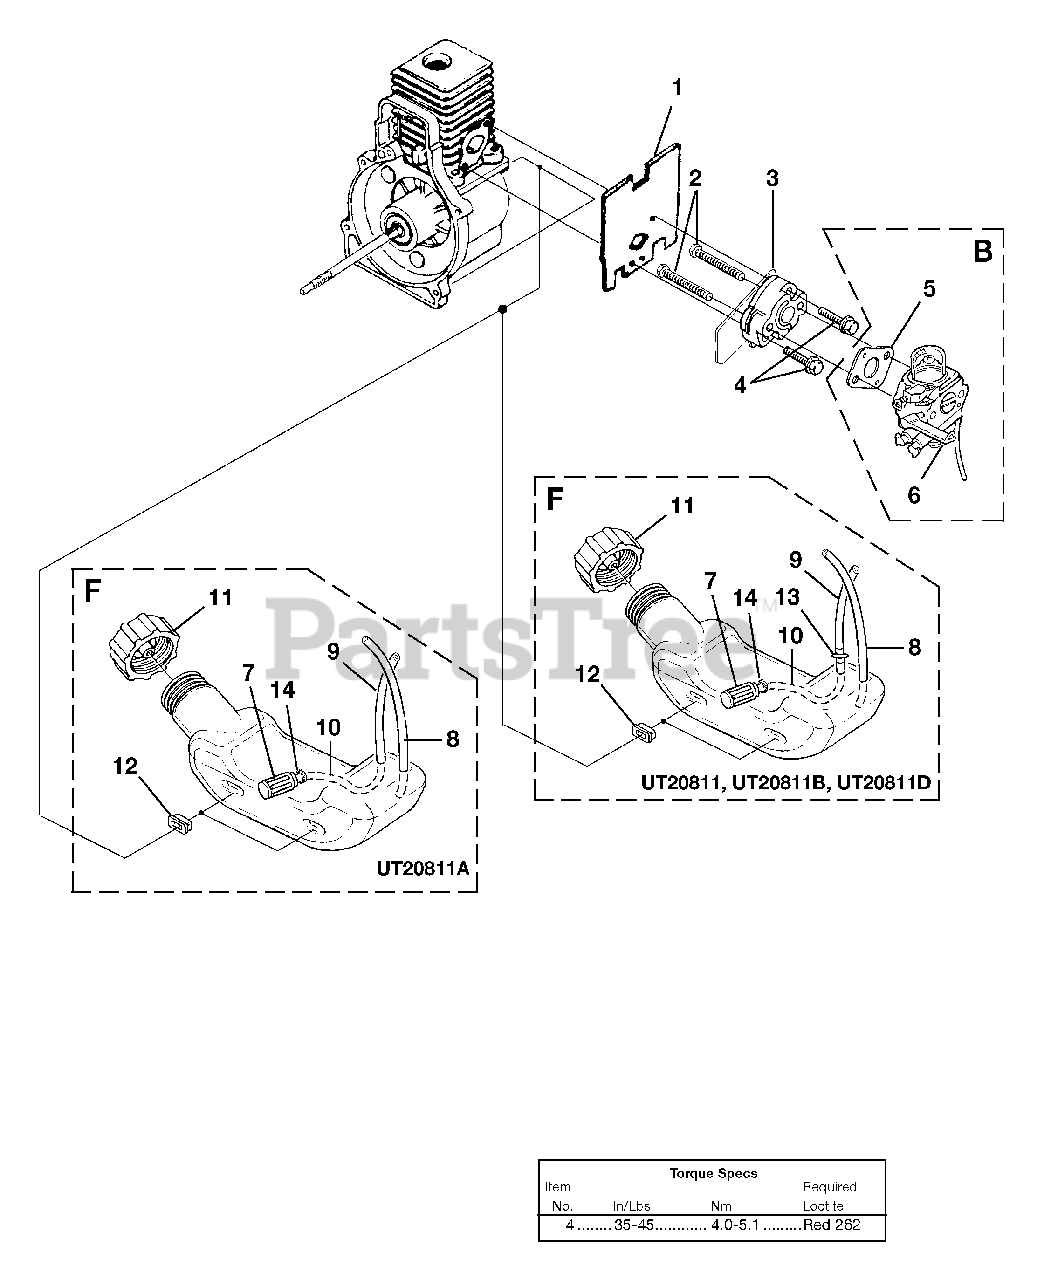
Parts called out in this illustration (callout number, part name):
1	GASKET-Heat Dam
2	SCREW-Machine (10-24 X 2 1/4")
3	HEAT DAM
4	SCREW-Sems (10-24 X 1")
5	GASKET-Carburetor
6	LEVER-Choke
7	FILTER-Fuel
8	TUBING-Rubber
8	TUBING-Rubber (6")
9	TUBING-Rubber
9	TUBING-Rubber (7.75")
10	TUBING-Rubber
11	FUEL CAP
12	BUMPER-Rubber
13	FITTING-Inline
14	CLAMP
B	CARBURETOR KIT
F	FUEL TANK ASSY. (UT20811 & B & D)
F	FUEL TANK ASSY. (UT20811A)
